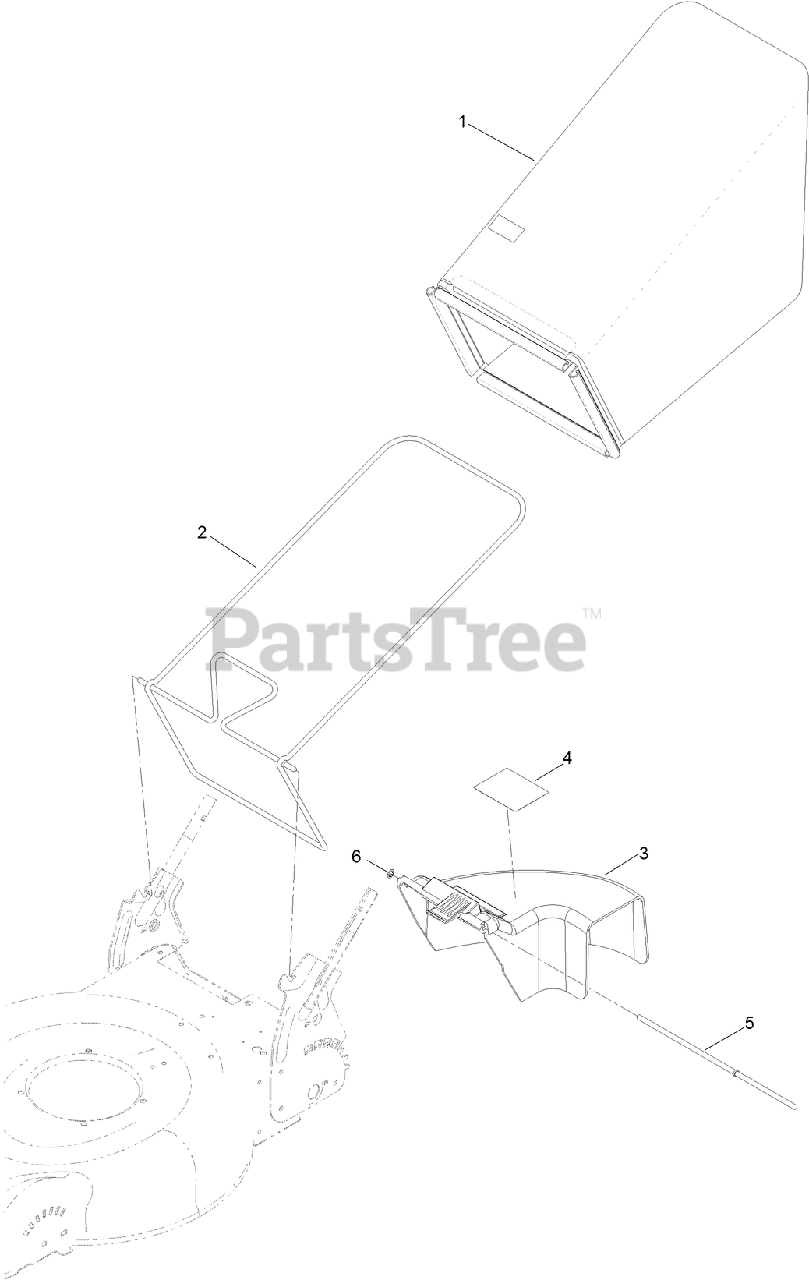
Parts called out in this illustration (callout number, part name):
1	GRASS BAG ASM
2	FRAME-BAG
3	REAR DEFLECTOR ASM
4	DECAL-WARNING
6	RING-RETAINING
